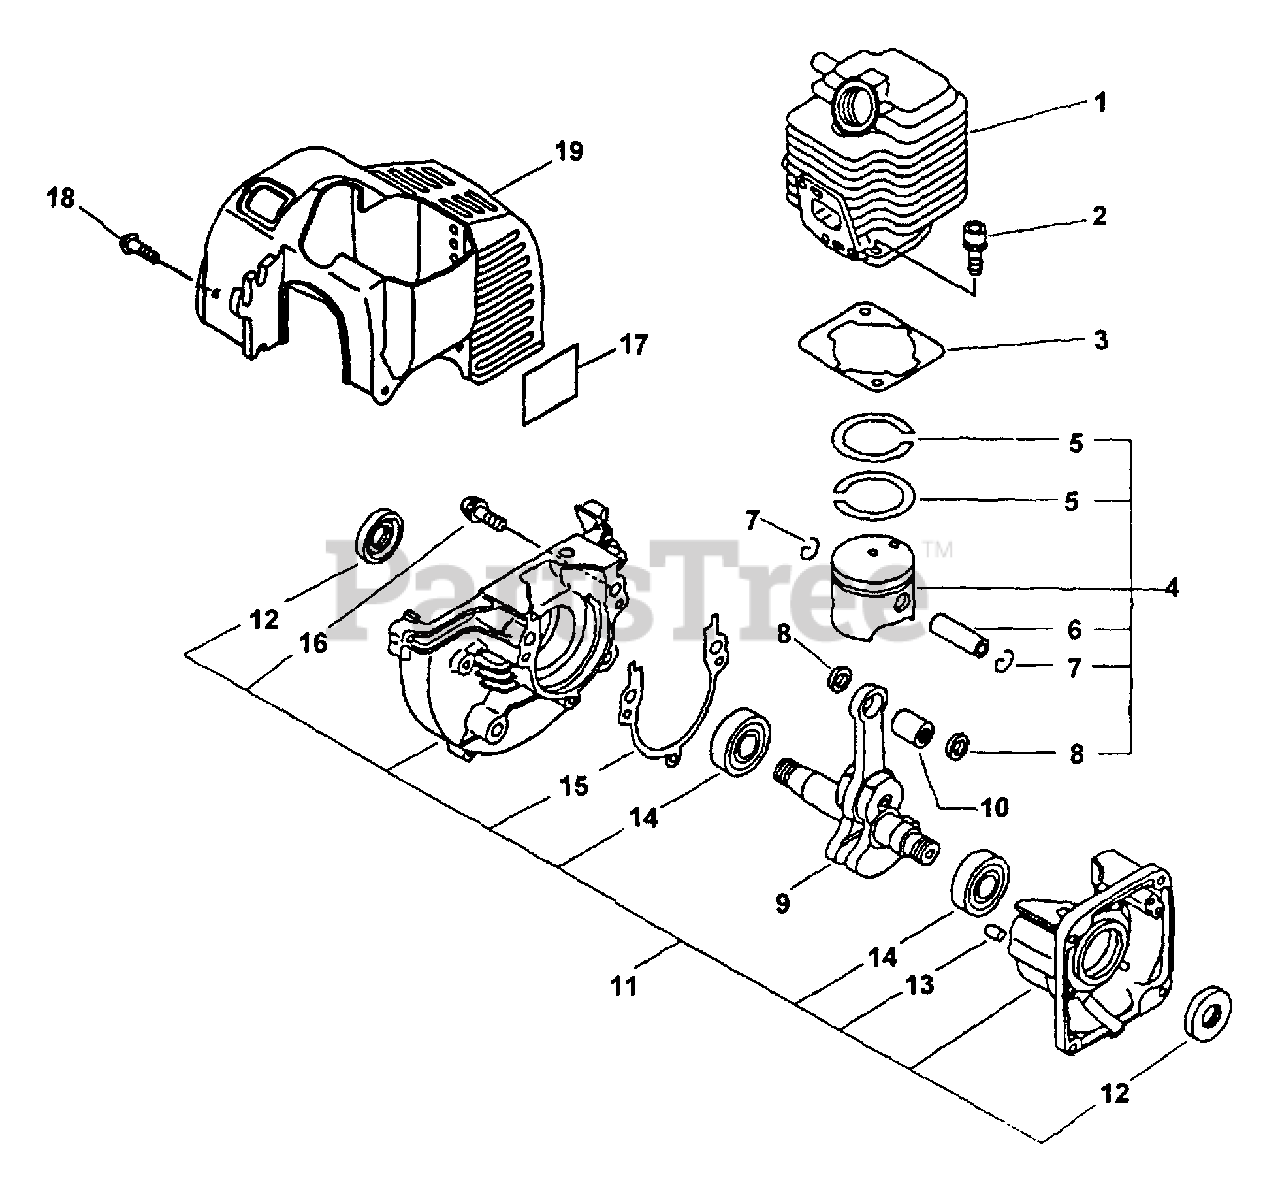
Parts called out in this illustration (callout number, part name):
1	CYLINDER
2	SCREW - 5X22
3	GASKET, CYLINDER
4	PISTON KIT
5	RING, PISTON
6	PIN, PISTON
7	RING, RETAINING
8	SPACER, PISTON
9	CRANKSHAFT ASSY
10	BEARING, NEEDLE
11	CRANKCASE KIT
12	SEAL, OIL
13	PIN - LOCATING
14	BEARING, BALL - 6201
15	GASKET, CRANKCASE
16	SCREW - 5X28
17	LABEL - MODEL EDR-2100
18	SCREW - 4X12
19	COVER, ENGINE - GRAY
